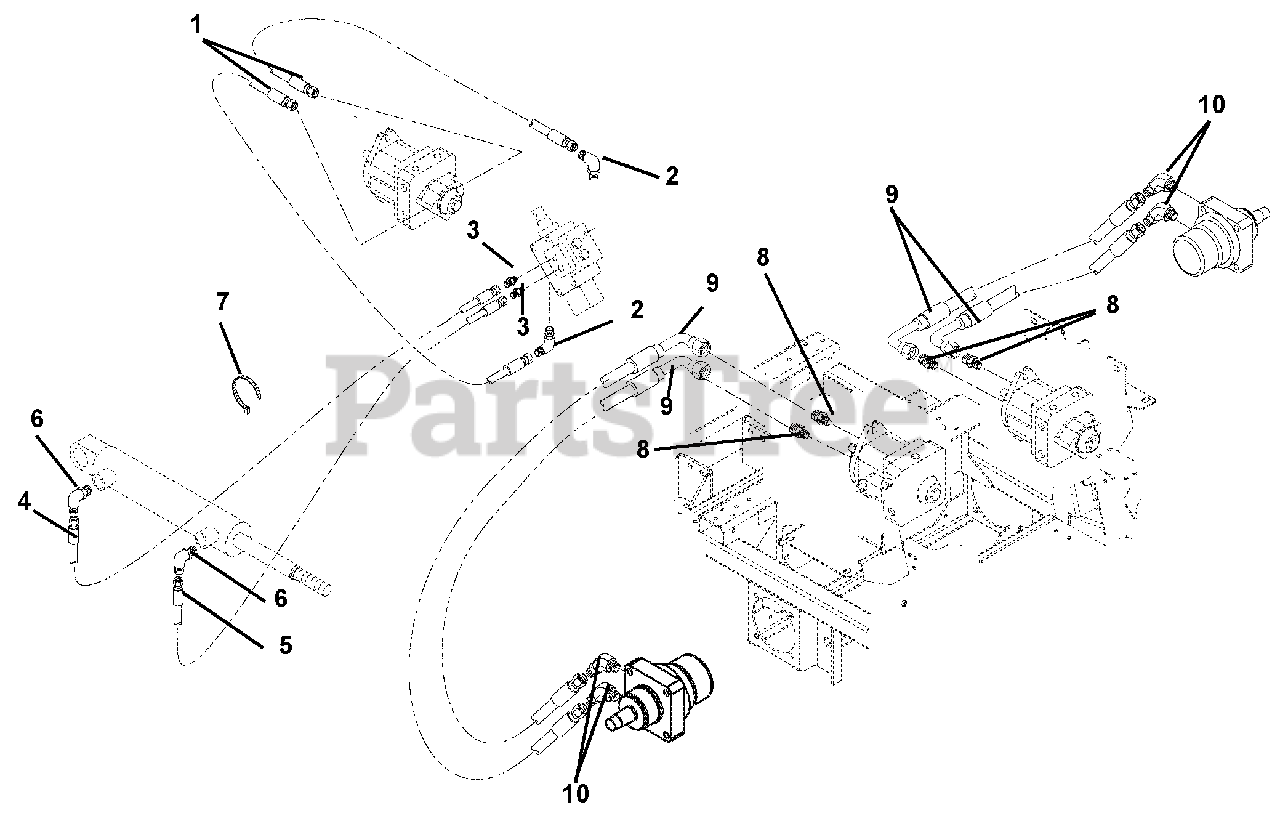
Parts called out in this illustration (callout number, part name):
1	Hose, Hydraulic
2	Hydraulic, Fitting Elbow
4	Hose, Hydraulic
5	Hose, Hydraulic
6	Fitting, Hydraulic
7	Cable Tie
8	Adapter, Face Seal 8 x 8 .50 O-Ring
9	Hose, Hydraulic .50
10	Adapter-Hydraulic Steel .875 to .75
